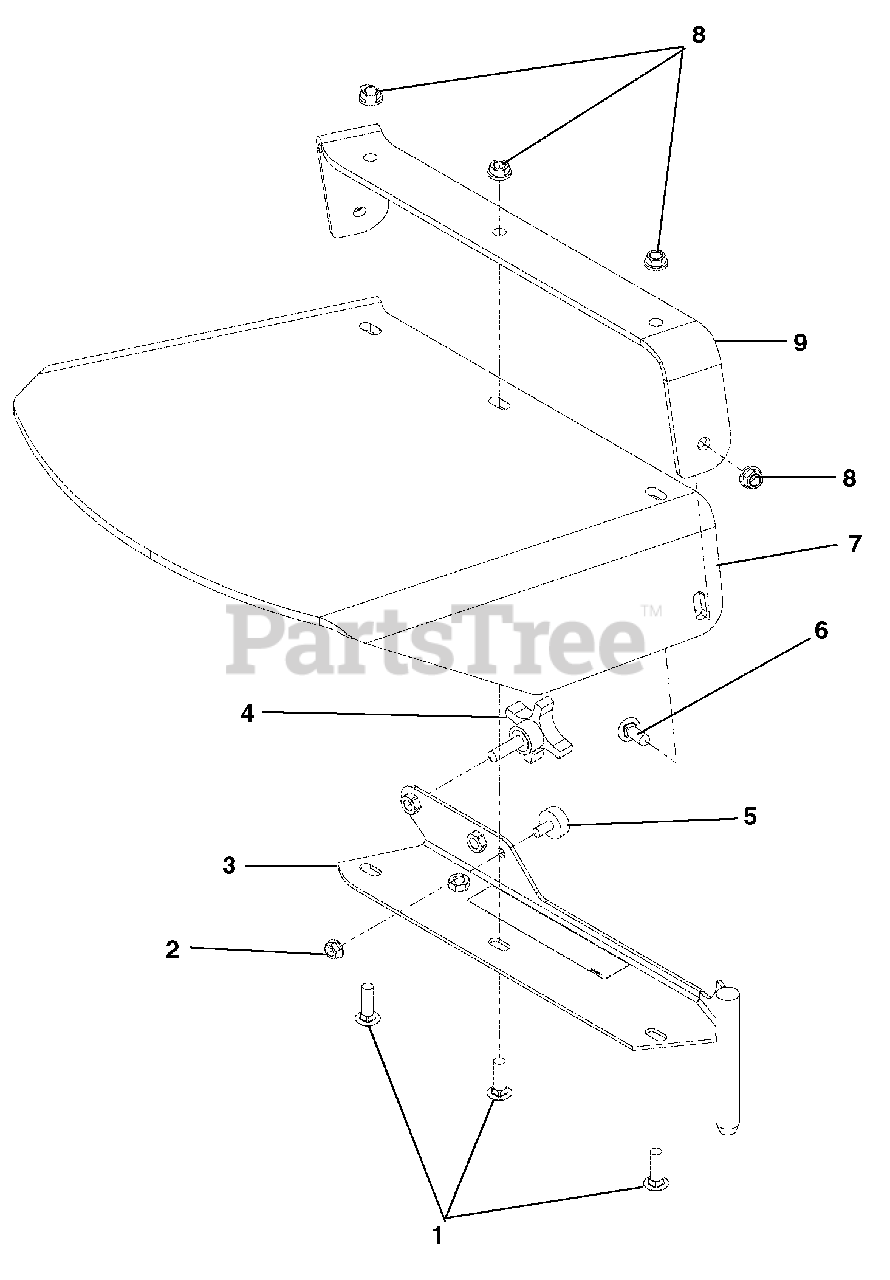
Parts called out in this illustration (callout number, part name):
1	Bolt, Round Head Square Neck .38-16 x 1.25 Grade 5
2	Locknut, .313-18 Whiz
3	Weldment, Discharge
4	Knob, .375 x 1.25-4 Prong
5	Bumper, Rubber
6	Bolt, Round Head Square Neck .38-16 x 1.00 Grade 5
7	Shield, Walk Rubber Discharge
8	Nut, Spin Lock Flange .375-16
9	Strap, Gravely Walk Rubber Discharge Chute
